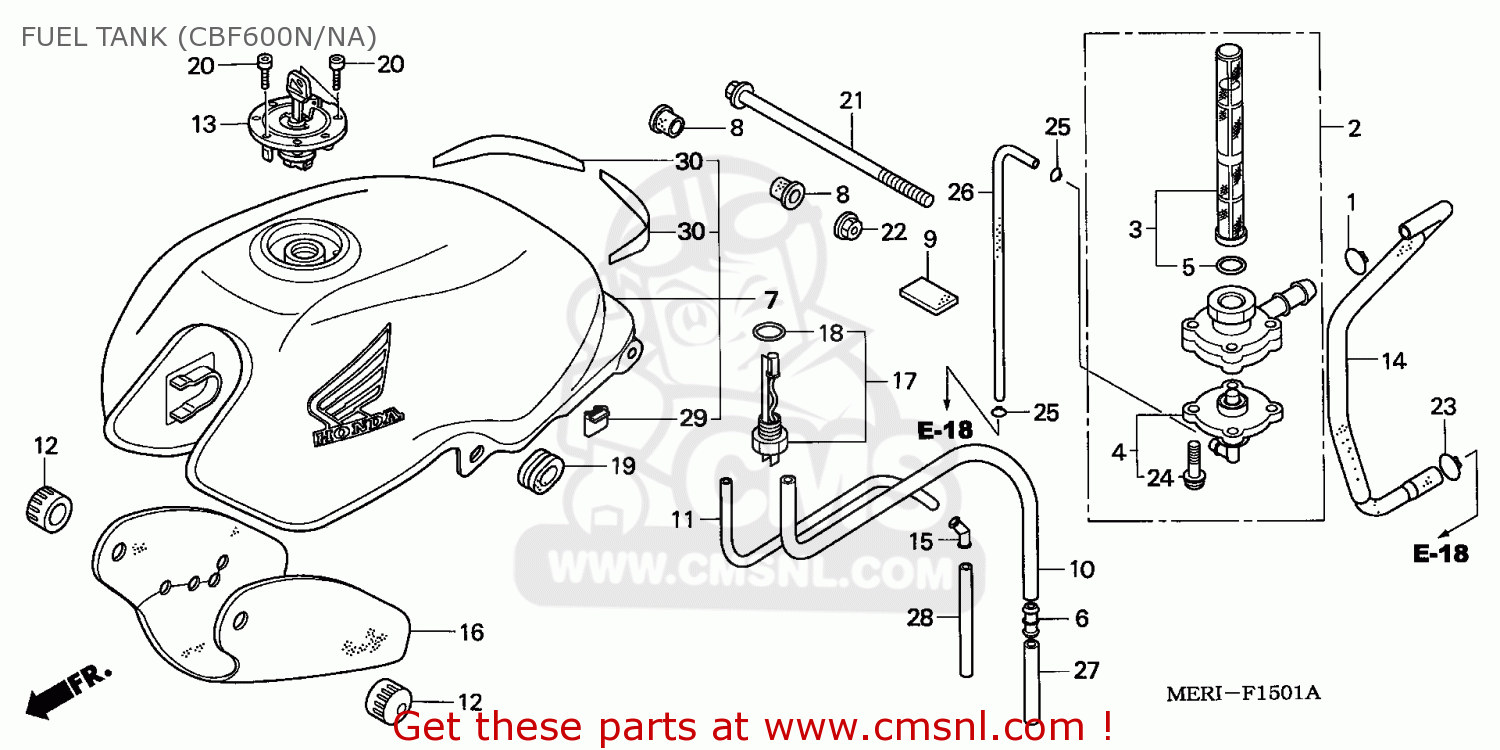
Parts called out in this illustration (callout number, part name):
1	CLIP, OIL DRAIN TUBE
2	AUTO COCK ASSY FU
3	SCREEN SET,FUEL S
4	COVER SET,COCK
5	O-RING
6	JOINT,TUBE
7	TANK SET, FUEL (WL)
8	CUSH,FUEL TANK RR
9	CUSH FUEL TANK RR
10	TUBE,DRAIN
11	TUBE,BREATHER
12	CUSHION,FUEL TANK
13	CAP COMP,FUEL FIL
14	TUBE,FUEL
15	JOINT,TUBE
16	RUBBER,HEAT GUARD
17	FUEL RES SENSOR
18	PKG,FUEL.RESERVE
19	CASE,GROMET
20	BOLT,SOCKET 4X21
21	BOLT,TANK HINGE
22	NUT,U.,6MM
23	CLIP,AIR/C BASE
24	SCREW-WASHER,4X16
25	CLIP B7,TUBE
26	TUBE,3.5X130
27	TUBE,8X220
28	TUBE,8X400
29	RUBBER, PROTECTOR
30	TAPE,TANK GUARD
